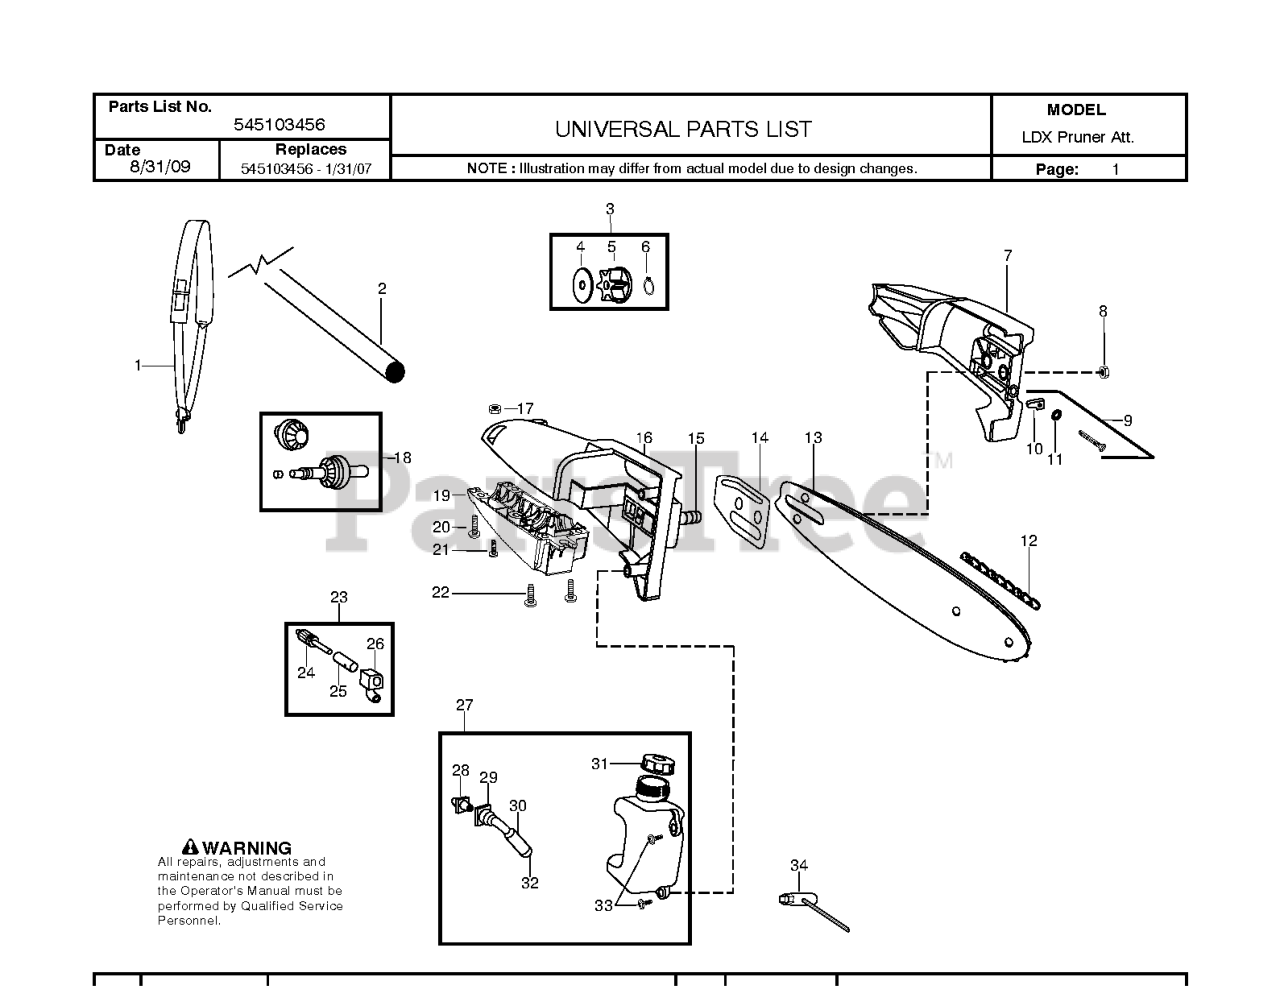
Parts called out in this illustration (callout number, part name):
1	Harness-w/o warning
2	KIT ASSY DRIVESHAFT PRUNER LDX
6	RING SPROCKET RETAINER
7	BAR CLAMP ASSY
9	KIT.RETAINER.BAR ADJUSTMENT
10	ADJUST PIN,BAR 36/41
12	Chain - 8"
14	PAD BAR PLATE
16	GEAR HOUSING UPPER
18	KIT GEAR ASSY
19	GEAR HOUSING LOWER
20	SCR 10-24 MS LDK PAN PH
21	SCREW-10-14 X 1/2 PLASTITE
22	SCREW-10-14 X 13/16 (PL
24	ASSY GEAR PLUNGER
27	ASSY OIL TANK PRUNER ATTACH
28	OIL PUMP FITTING
29	LINE OIL INTAKE
30	FILTER
31	CAP OIL
32	PLUG
34	WRENCH-BAR
